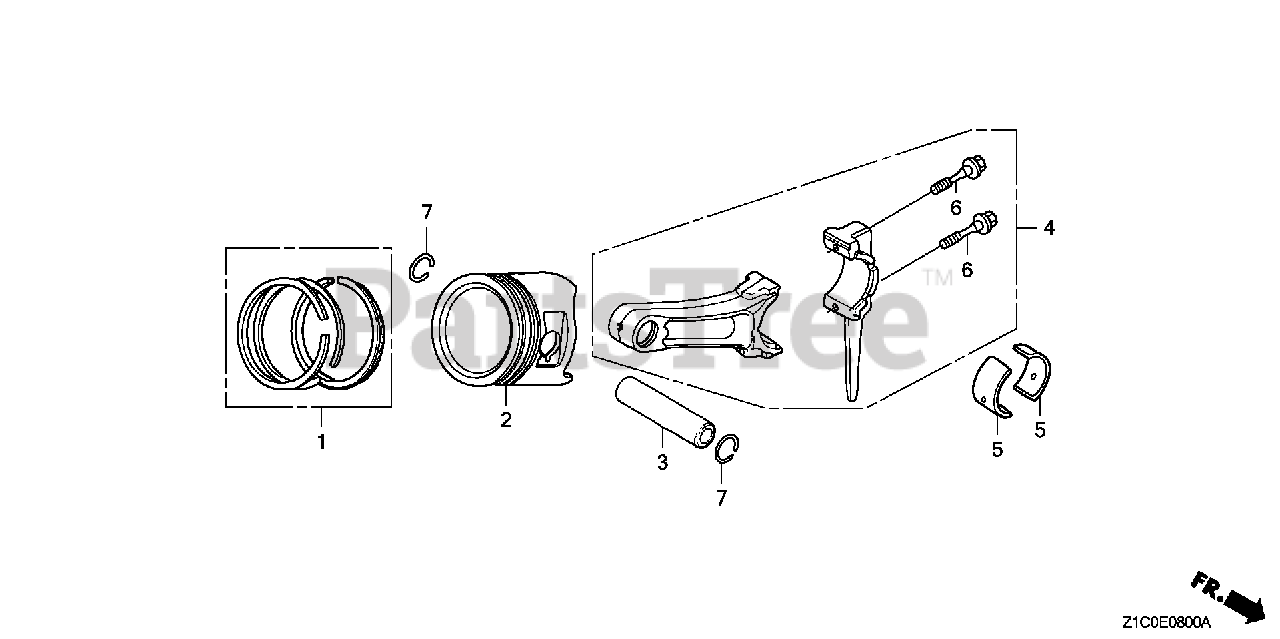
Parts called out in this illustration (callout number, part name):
1	RING SET, PISTON (STD.) (RIKEN)
1	RING SET, PISTON (0.25) (RIKEN)
1	RING SET, PISTON (0.50) (RIKEN)
1	RING SET, PISTON (0.75) (RIKEN)
2	PISTON (STD)
2	PISTON (OS 0.25)
2	PISTON (OS 0.50)
2	PISTON (OS 0.75)
3	PIN, PISTON
4	ROD ASSY., CONNECTING (0.25 LOWER SIZE)
4	ROD ASSY., CONNECTING (STD)
6	BOLT, CONNECTING ROD
7	CLIP, PISTON PIN (20MM)
